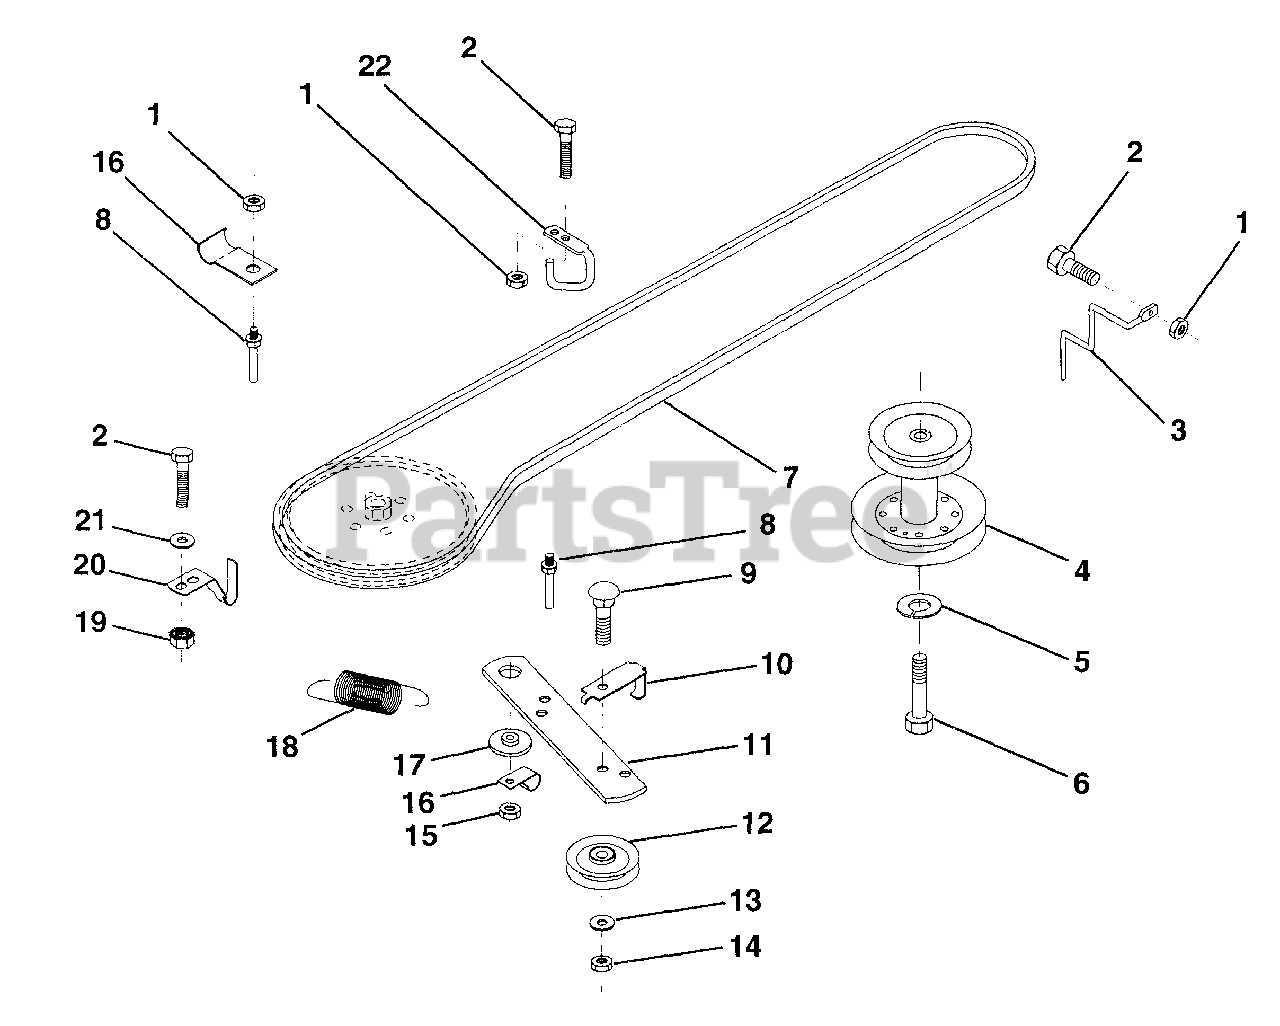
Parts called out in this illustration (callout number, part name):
1	Nut, Hex, Crownlock 5/16-18
2	Bolt, Hex Head 5/16-18 UNC x 3/4
3	Keeper, Mower Drive Belt, R.H.
4	Pulley, Engine
5	Washer, Lock 7/16
6	Bolt, Hex Head M10 x 1.5 x.75mm
7	V-Belt, Ground Drive
8	Keeper, Ground Drive Belt
9	Bolt, Carriage 3/8-16 UNC x 1-1/2
10	Keeper, Ground Drive Belt, Idler
11	Clutch Arm, Ground Drive
12	Idler, Flat
13	Washer 13/32 x 13/16 x 16 Gauge
14	Nut, Centerlock 3/8-16 UNC
15	Nut, Crownlock 3/8-16 UNC
16	Clip, Insulated
17	Spacer, Retainer
18	Spring Extension
19	Nut, Keps 5/16-18 UNC
20	Keeper, T/A Ground Drive Belt
21	Washer 11/32 x 5/8 x 16 Ga.
22	Keeper, Frame Ground Drive Belt
